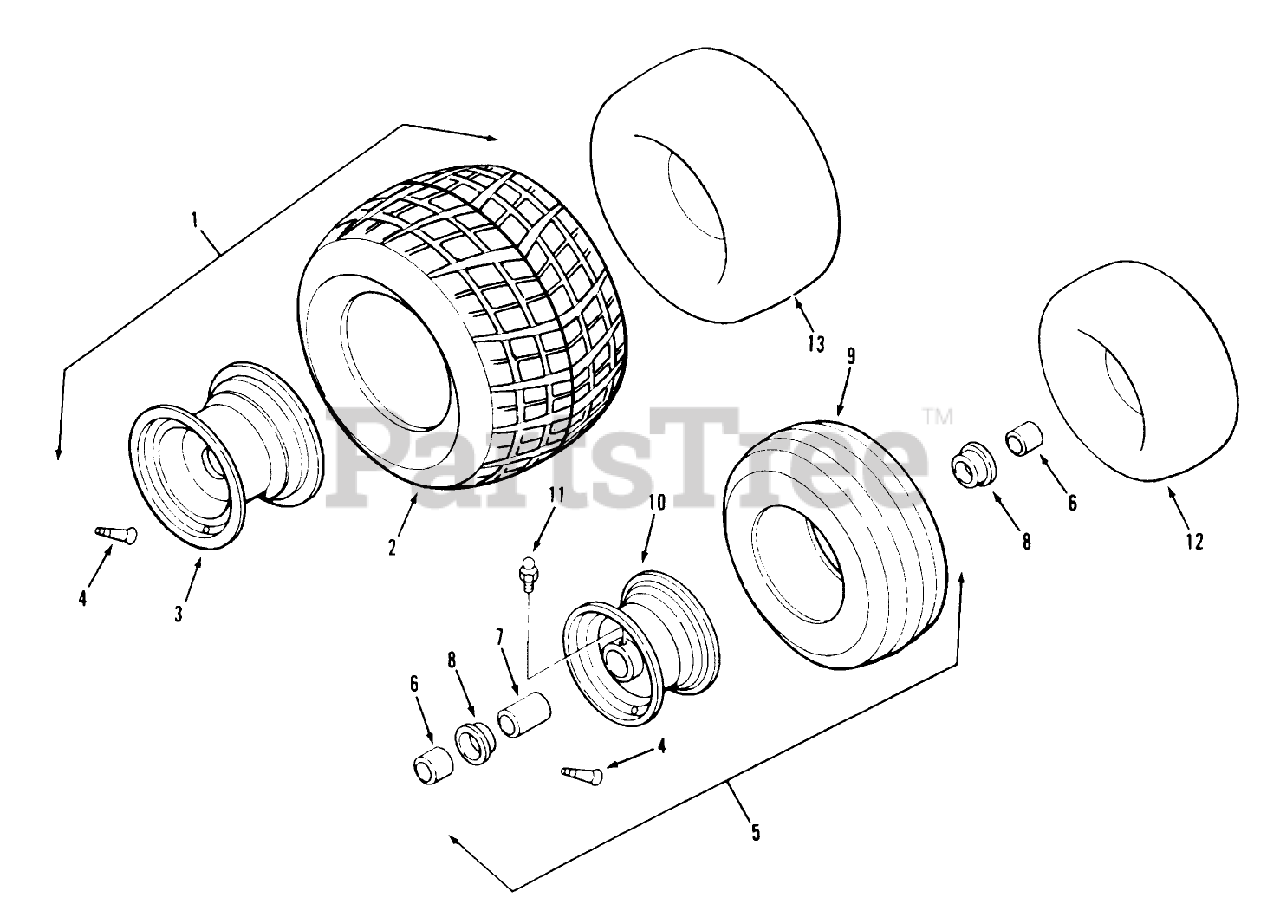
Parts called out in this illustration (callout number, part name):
2	TIRE 22 X 11.00-8
3	Wheel-Rear, Silver
4	VALVE
6	SPACER
7	SPACER FRT WHEEL INN
8	BEARING BALL
9	TIRE-FRT 13X5.00-6
10	WHEEL FT SLUV 10239K
11	FITTING-GREASE
12	INNER TUBE
13	Tube-Rear
